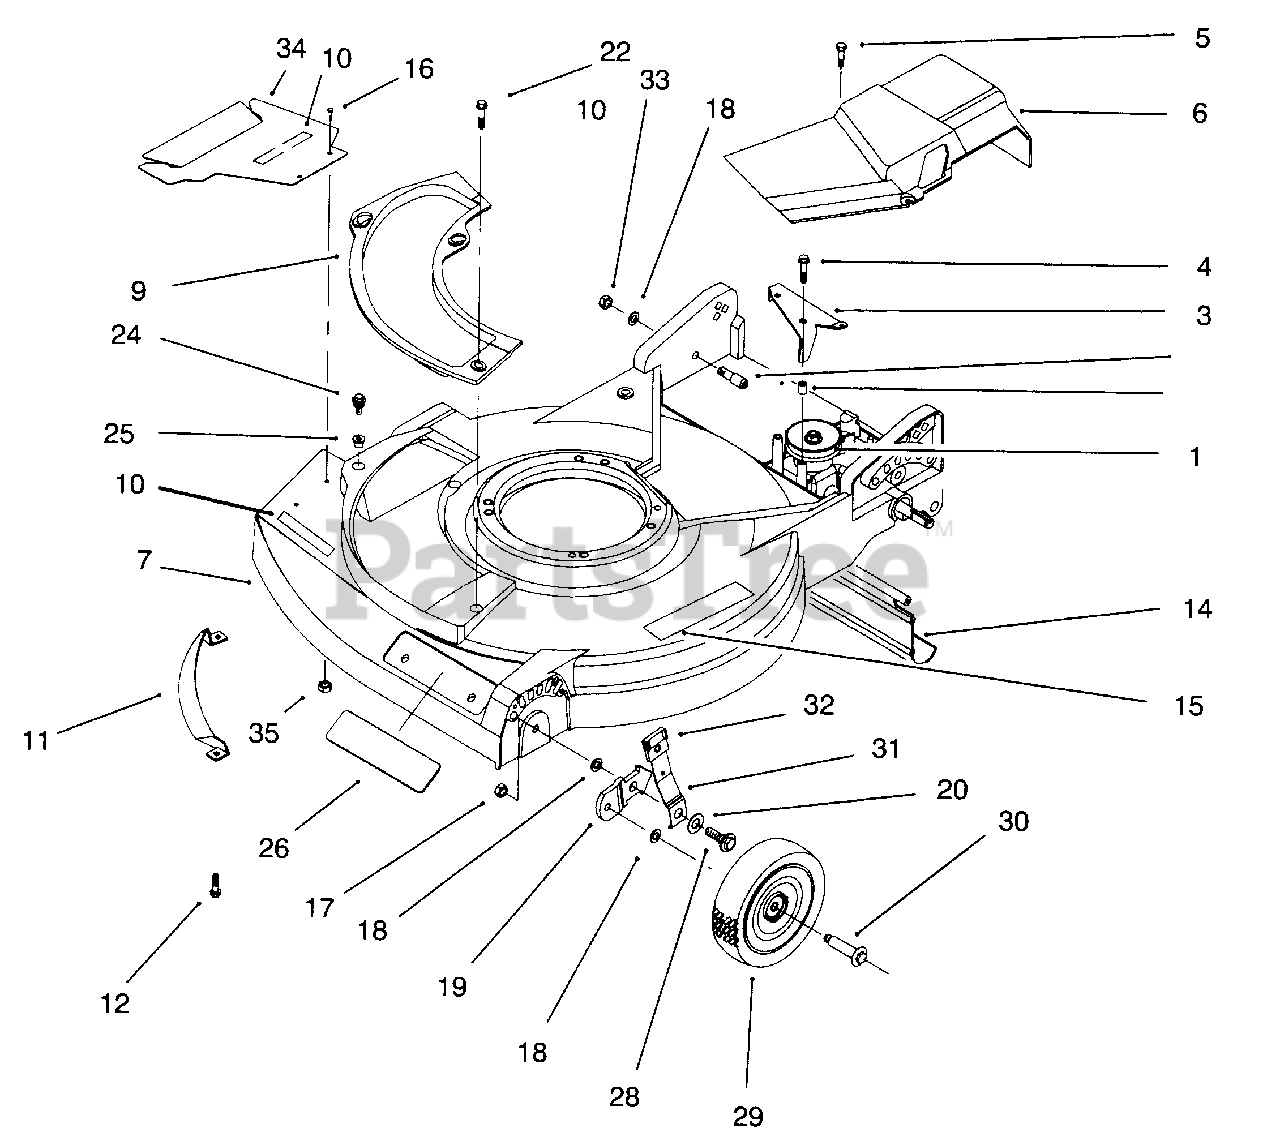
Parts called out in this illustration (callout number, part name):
1	Gear Case Assembly
2	Bushing-Spacer
3	Bracket-Actuator
4	Screw
5	Screw-Thr'd Form
6	Cover-Drive
7	Housing (Incl. Ref. #10, & 15)
9	Plate-Cover
10	Decal-Danger
11	Toe Bar
12	Screw-Hex Washer Hd.
14	Shield-Trailing
15	Decal-Warning
16	Screw-Hex Hd. Cap
17	Nut-Lock
19	Bracket-Wheel Height Adj.
20	Washer-Belleville
21	Bolt-Shoulder
22	Screw-Hex Hd. Cap
24	Screw-Sems Thr'd Form
28	Bolt-Shoulder
29	Wheel & Tire Assembly-6"
30	Bolt-Wheel
31	Spring Arm Ass'y-Front
32	Knob-Height Adjust
33	Nut-Lock
34	Guard-Plate
35	Nut-Lock
